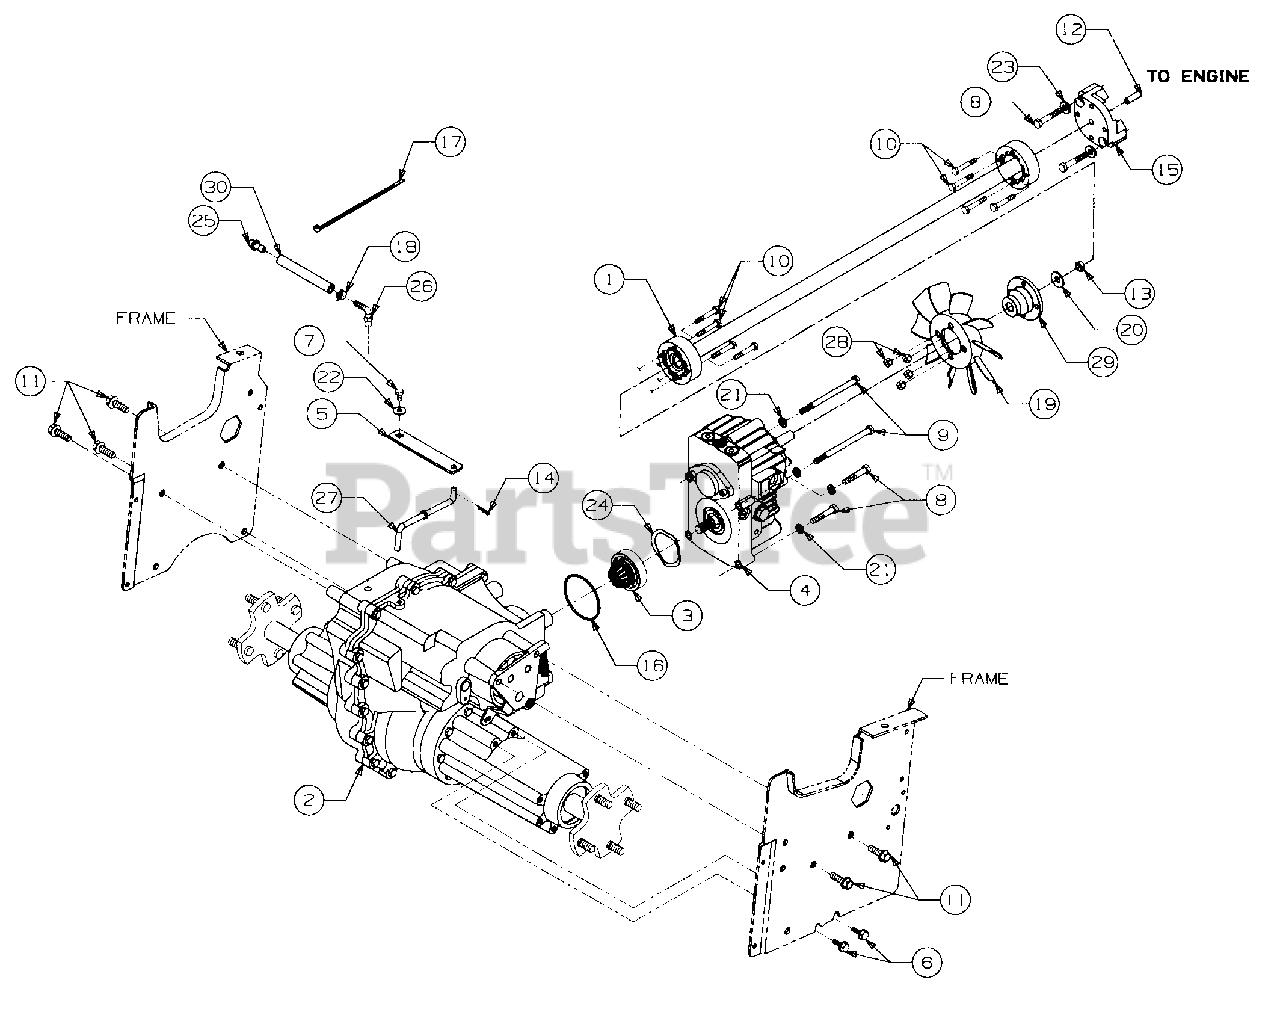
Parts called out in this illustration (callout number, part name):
1	Shaft Assy, Drive, 29.06 Lg
2	Transmission, Hydro
3	Pinion Assy, Input
4	Pump, Hydrostatic
5	Arm, Hydro Dump
6	Screw, Hex Wash Sf-Tapp 5/16-18 x .75 Lg
7	Screw, Hex Wash, TT-Tapp, 1/4-20 x .75 Lg GR5
8	Screw, Hex Cap, 5/16-18 x 1.75 Lg GR5
9	Screw, Hex Cap, 5/16-18 x 4.5 Lg GR5
10	Bolt, Hex Patch, 1/4-20 x 1.62 Lg GR5
11	Screw, Hex Wash Tapp 3/8-16 x 1.25 Lg
12	Pin, Locating
13	Nut, Hex Center Lock Jam 3/8-24
14	Pin, Internal Cotter, 5/16 Dia x 1.12 Lg
15	Adapter, Drive Shaft
16	O-Ring, 2.75 x .103
17	Tie, Self-Clinch Cable
18	Clamp, Hose
19	Fan, 10 Blade Cooling
20	Washer, Bell, .380 x .88 x .062 Thk
21	Washer, Lock, 5/16
22	Washer, Bell, .265 x .75 x .062 Thk
23	Washer, Flat, .312 x .750 x .119 Thk
24	Washer, Spring Wave, 1.96 x 2.44 x .06 Thk
26	Fitting, Elbow
27	Rod, Hydro Disengagement
28	Nut, Fan, 1/4-20
29	Adapter, Pump
30	Line, Fuel, 7 in. Lg
